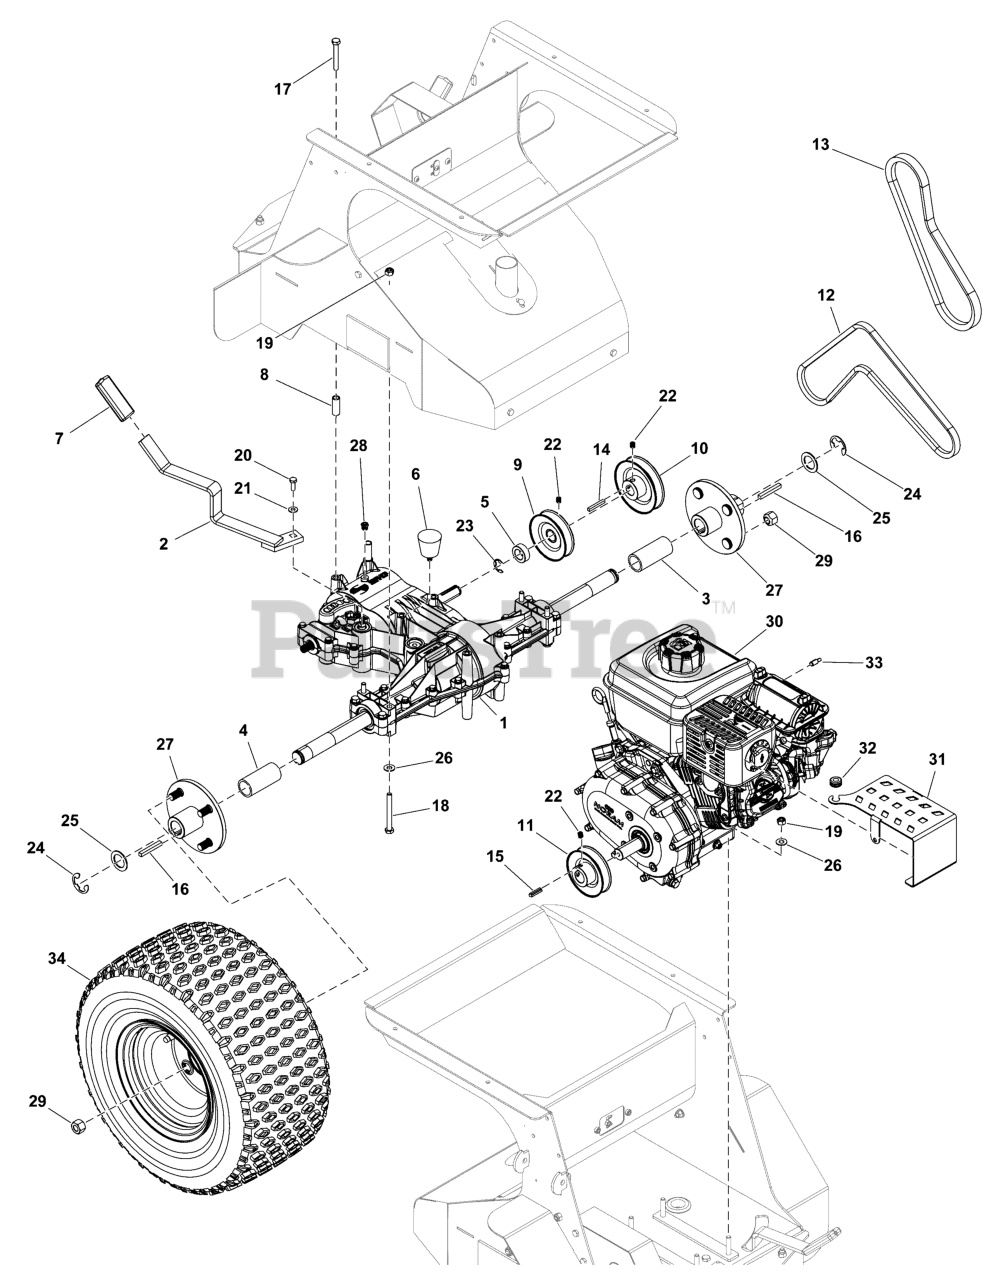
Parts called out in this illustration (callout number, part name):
1	TRANSMISSION, PEERLESS 855-007D
2	WELD,LEVER,GEAR SHIFT, ROVER
3	SPCR-PVC 1.049" X 1.315" X 3.000
4	SPCR-PVC 1.049" X 1.315" X 2.850"
5	SPCR-UHMW .765" X 1.250" X .450"
6	BUMPER, 1.188OD X 1.50LG W/.3125-18 STUD
7	GRIP, .188" X 1.00" ID X .150" THK CLSD CELL FOAM
8	SPCR-SS, 304 0.370" X 0.500" X 1.350"
9	PULLEY, 3.50" O.D. x 0.750" I.D. V, A/B
10	PULLEY, 4.00" O.D. x 0.750" I.D. V, A/B
11	PULLEY, 3.50" O.D. x 0.875" I.D. V, A/B
11	PULLEY, Crankshaft
12	BELT, A-SEC, A39
13	BELT, V, B 29.80EL OHR ETH, PLY CD
14	KEY, .188" SQ. X 1.50" SS303
15	KEY, .188"-.250" STEPPED X 1.00" LONG SS 304
15	KEY, Drive Pulley
16	KEY, .250" SQ. X 2" SS188
17	SCR-CAP, HEX .3125"-18 X 2.250" SS188
18	SCR-CAP, HEX .3125"-18 X 3.000" SS188
19	NUT-HEX-NYLK, 0.3125"-18 SS188
20	SCR-CAP, HEX .250"-28 X 0.750" SS188
21	WSHR-SS, BLV .281"X.875"x.066
22	SCR-SH, SET .3125"-18 X .375" KCPT SS188
23	E-RING, .750" SHAFT YZ
24	E-RING, 1.000" SHAFT YZ
25	WSHR-STL, FLT 1.000"X1.500"X.075" MAB ZP
26	WSHR-STL, FLT .343" X .750" X .050" SPC SS188
27	HUB, 1.00" BORE 4-BOLT X 4.00" BC
28	BREATHER VENT, .125"-27 PFT X .4375" HEX
29	NUT-LUG, .500"-20 ZP
31	PLATE, MUFFLER SHIELD VG160 STAMPED MFLR
32	GROMMET, 0.375" I.D., FIT 0.500" HOLE
33	CONNECTOR, FEMALE BLT 14-16 AWG
34	ASM, WHEEL&TIRE 18" X 9.50" W/ANTI-FREEZE
